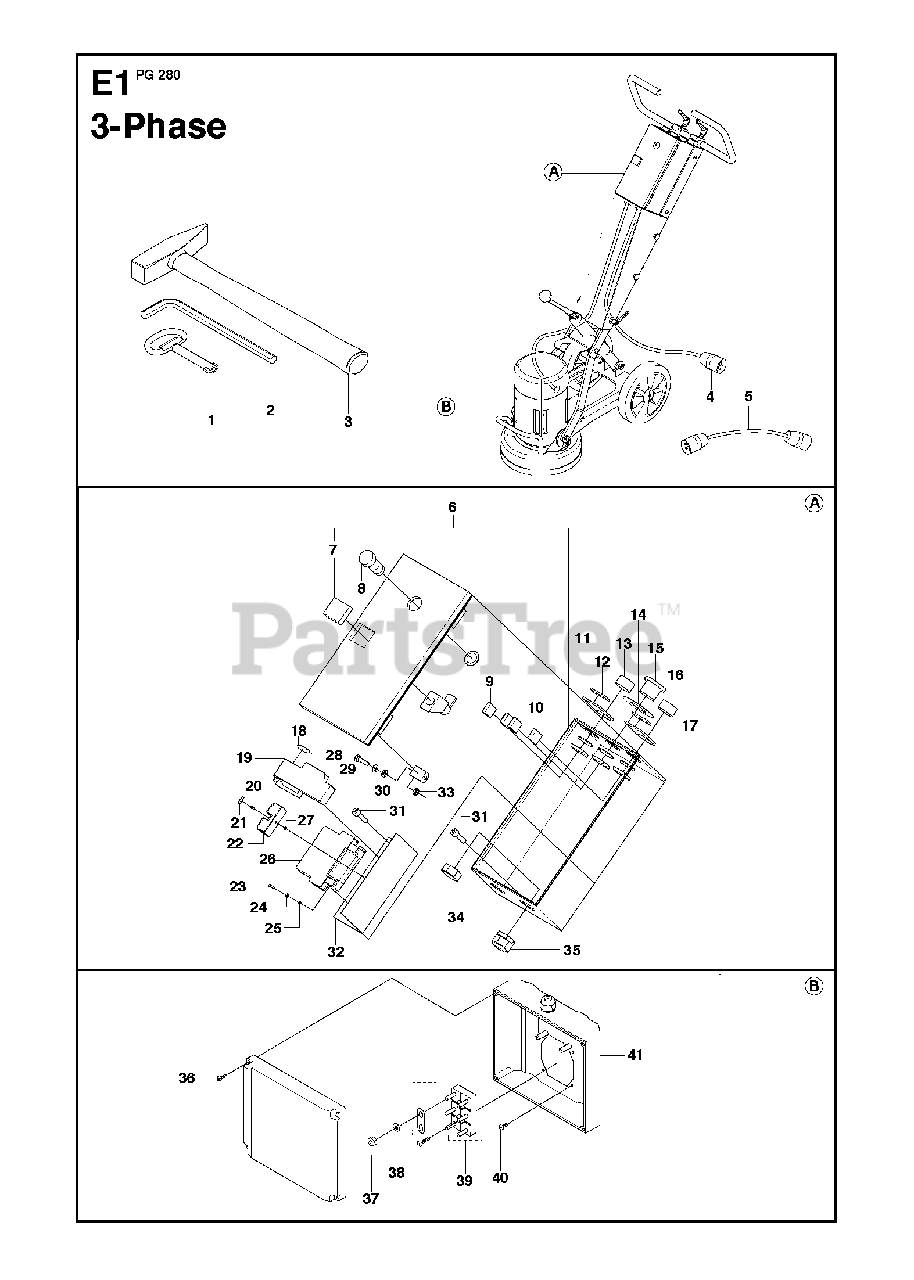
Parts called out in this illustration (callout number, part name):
25	HEXAGON LOCKING NUT
27	HEXAGON LOCKING NUT
28	SCREW EHHM
